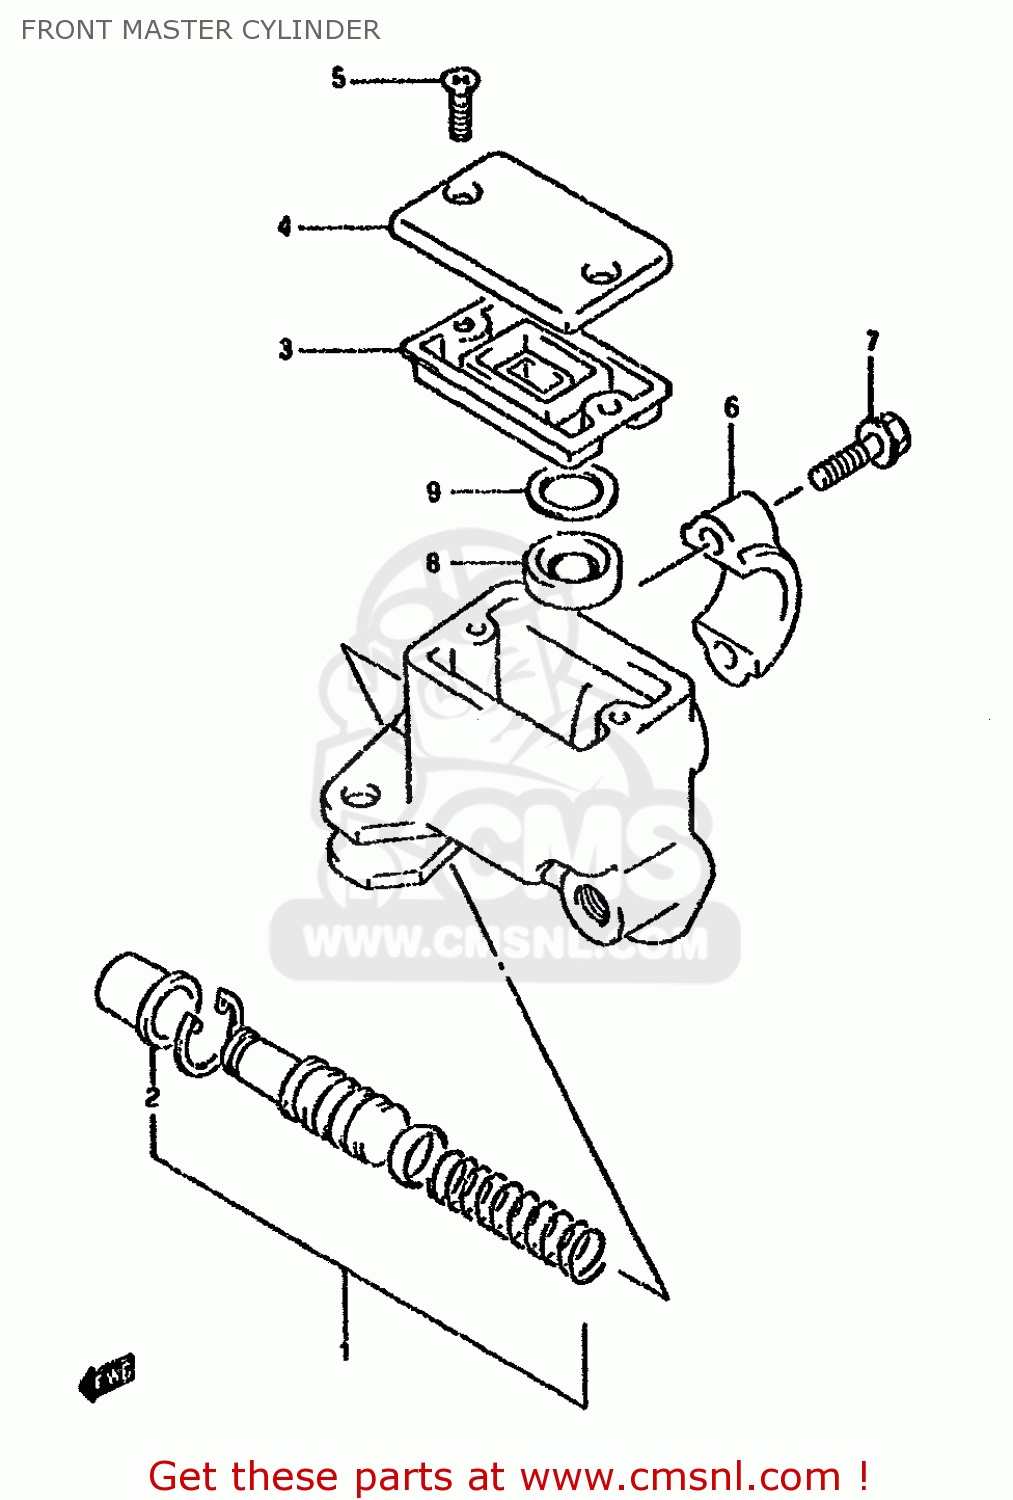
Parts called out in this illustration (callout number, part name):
1	PISTON/CUP SET
2	BOOT
3	DIAPHRAGM
4	CAP
5	SCREW
6	HOLDER
7	BOLT(6X25)
8	SEPERATOR
9	PLATE
